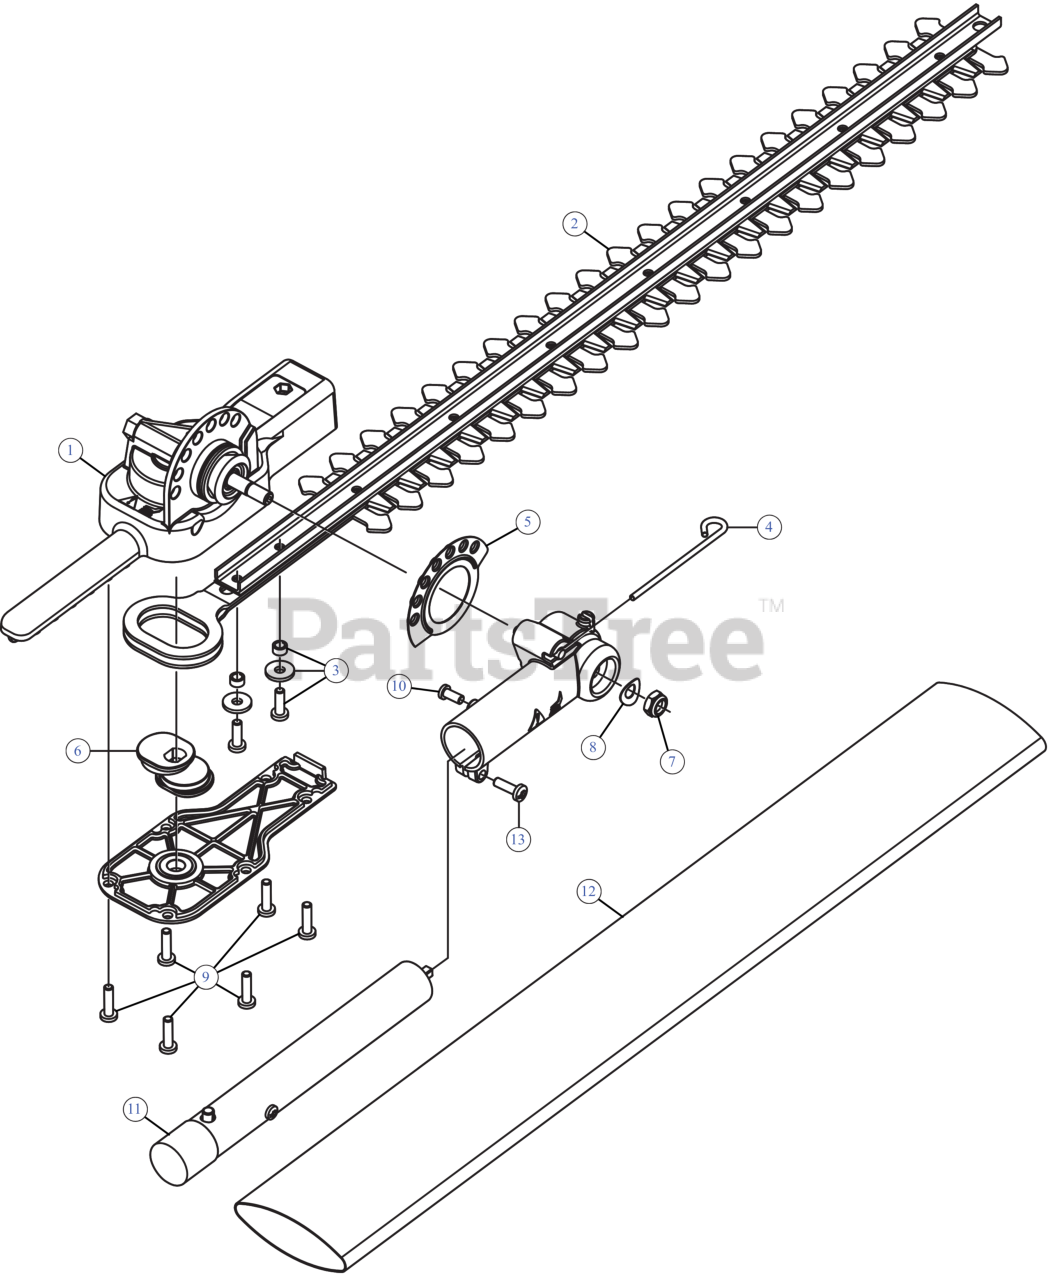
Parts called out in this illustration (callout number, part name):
1	GEARBOX ASSEMBLY
2	BLADE ASSEMBLY
3	BLADE HARDWARE
4	LOCKING LEVER PIN
5	SPACER DETENT SHM
7	NUT 5/16-24
8	SHAKE PROOF WASHER
9	SCREW - 10-24X.625 PAN HEAD
10	SCREW 8-32X.437
11	BOOM ASSEMBLY
12	BLADE COVER
13	SCR, M5 x 15.8MM
